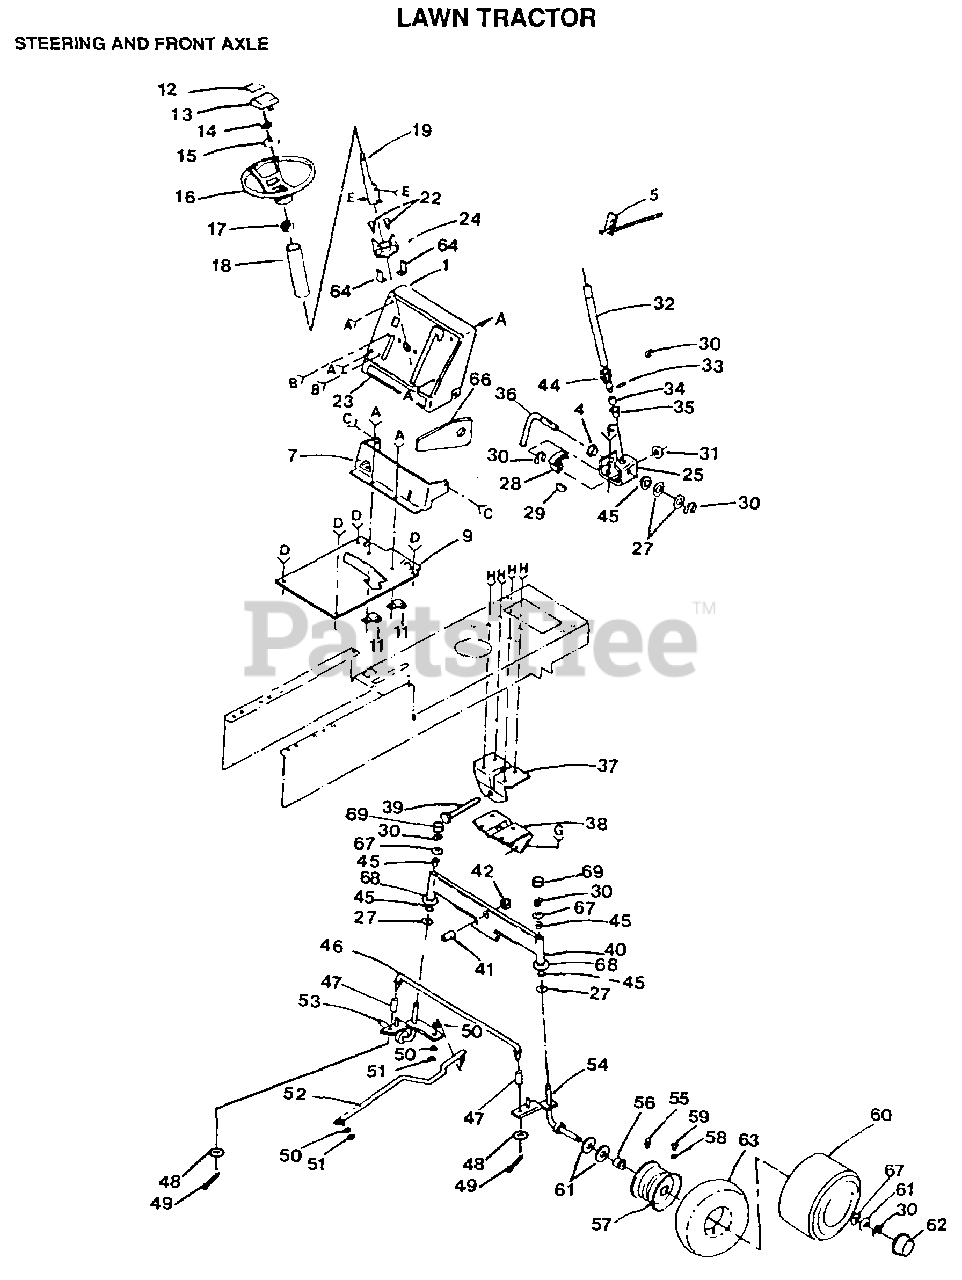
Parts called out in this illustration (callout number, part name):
4	NYLINER T
7	DASH-LOWER LT
11	CLIP T
13	INSERT-WHEEL LT
15	WASHER
17	ADAPTER LT
19	STEERING SHAFT
24	BUSHING T
27	WASHER .T
28	GEAR.SECTOR.HYT
29	KEY-WOODRUFF LT
30	RING
32	STEERING SHAFT T
34	SHAFT SPACER LT
35	BUSHING
36	ROD STEERING T
37	SUPPORT-SADDL T
38	SUPPORT.SADDLE.FT
39	BOLT LT
41	BEARING
42	"NUT-LOC,FLANGE LT"
44	GEAR PINION T
45	COL. SRTG. BEAR.
48	WASHER
49	COTTER PIN
50	LOCKWASHER
52	LINK-DRAG LT
53	SPINDLE-LH LT
55	FITTING LT
56	"FLANGE, BEARING"
58	VALVE CAP
59	VALVE STEM LT
61	WASHER
62	HUB CAP
63	TUBE.5.3/4.5/6
64	RETAINER T
67	WASHER
68	WASHER
69	CAP
